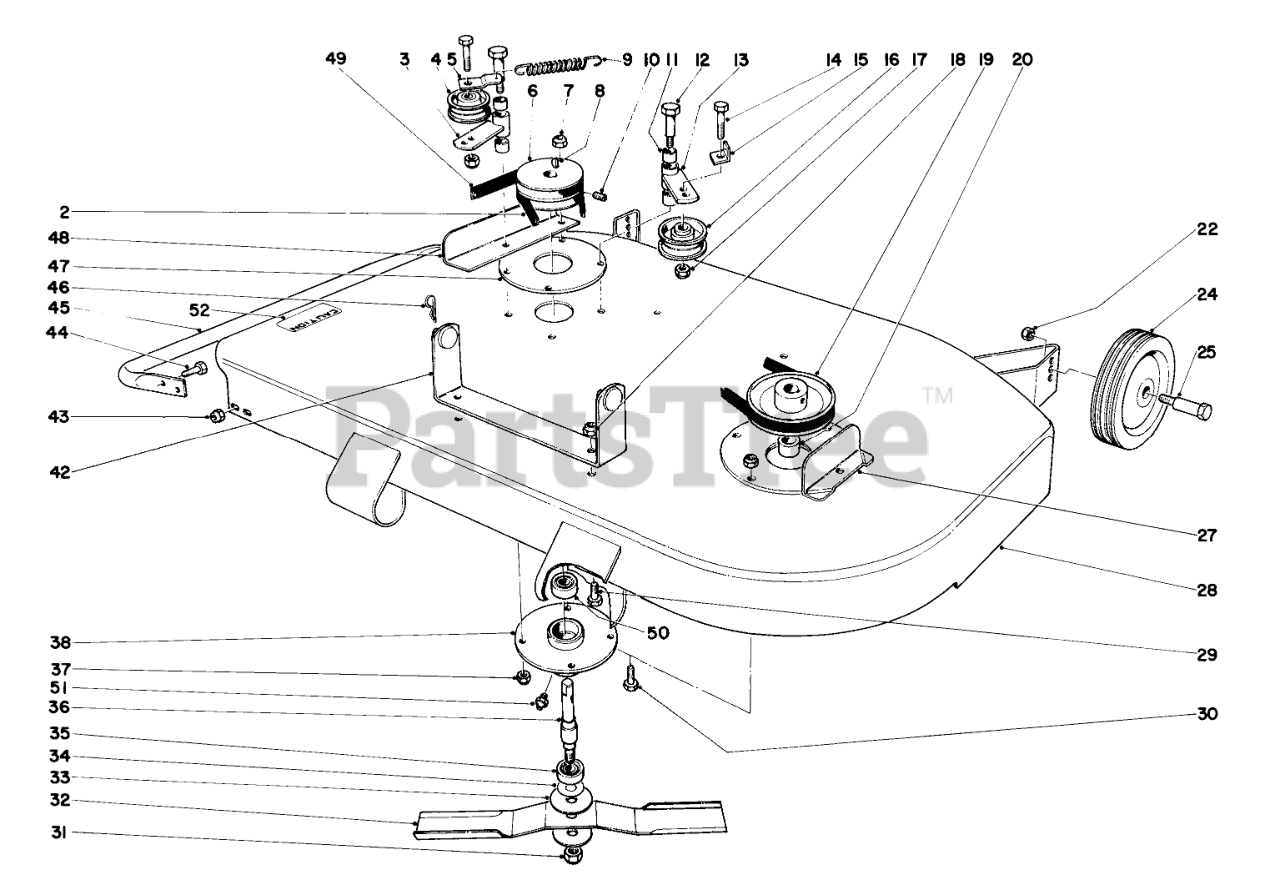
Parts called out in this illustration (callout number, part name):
2	Belt
3	Idler Plate Incl. Ref. #11
4	Flat Idler
6	BLD SPDLE PULLEY (MACH)
7	Nut
8	KEY-WOODRUFF
9	Spring Tension
10	SCREW-SET, HSH
11	Bushing
12	SHOULDER BOLT
13	Idler Plate
14	SCREW-HH
16	Pulley
18	Nut
19	Pulley
20	Spacer
24	Wheel
27	Belt Guard
28	Housing Assembly
29	SCREW-HH
30	SCREW-HH
32	Blade
33	WASHER
34	WASHER
35	Bearing
36	Blade Spindle
37	Nut
38	Spindle Housing
42	Height Adjustment Bracket
44	SCREW-HH
45	Blade Guard
46	PIN-COTTER
47	Washer
48	Guard
50	.6693 RP BALL BEARING
51	FITTING-GREASE
52	Decal
